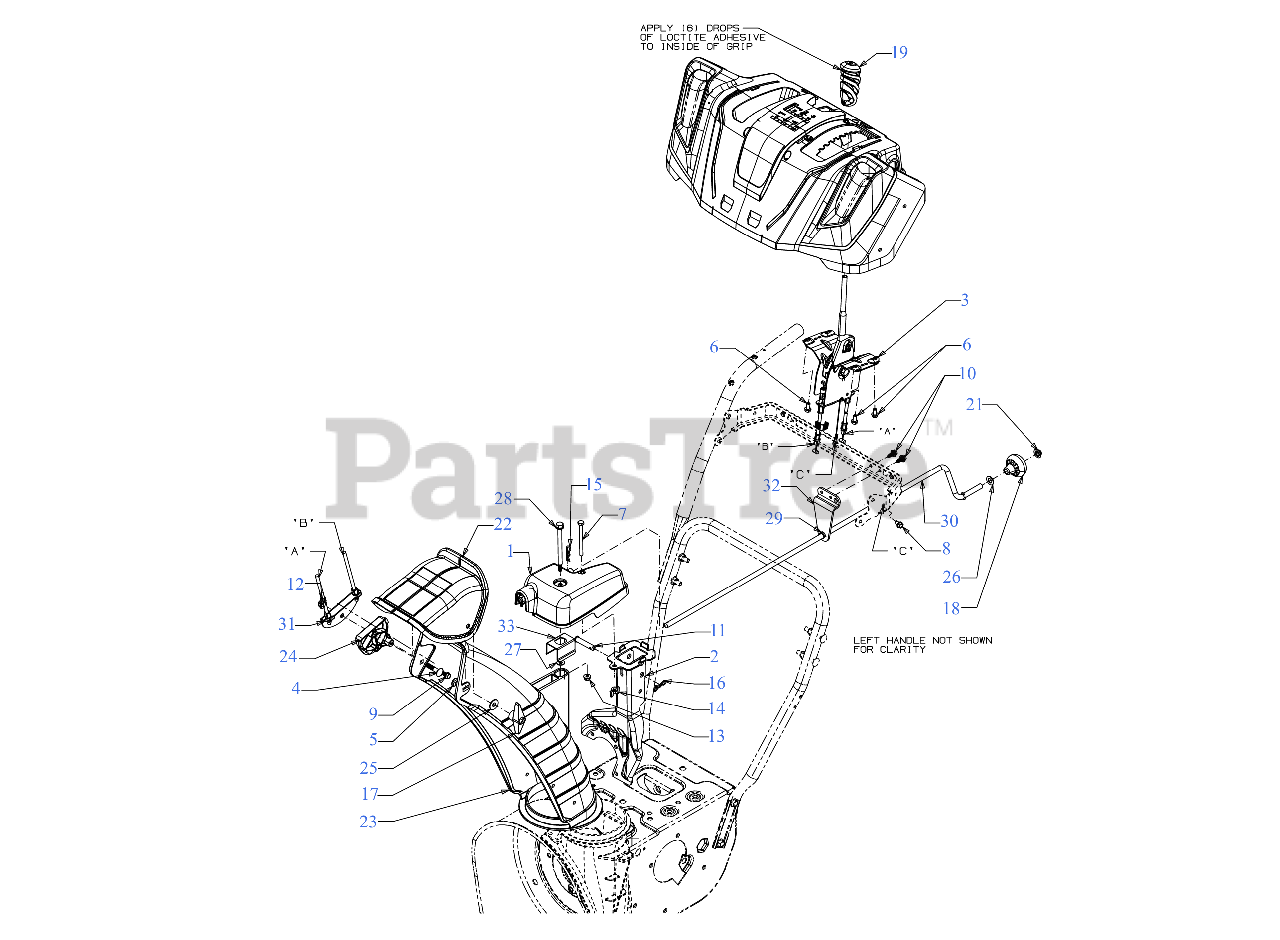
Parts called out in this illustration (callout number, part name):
1	GEARBOX ASSEMBLY
3	CHUTE CONTROL
4	CARRIAGE BOLT 5/16-18 x 1.50
5	CARRIAGE BOLT 5/16-18 x 1
6	HEX SCREW 1/4-15 x .50
7	SCREW 1/4-20 x 3.0 GR5
8	SCREW 1/4-20 X.500
9	SCREW 1/4-15 x .750
10	SCREW 1/4-20X.625
11	CLEVIS PIN 3/8 x 1.87
12	FLANGE LOCK NUT 5/16-18
13	FLANGE LOCK NUT
14	WING NUT 1/4-20
15	INTERNAL COTTER PIN-1/2 DIA
16	BOW TIE COTTER PIN 1/4-5/16
17	WING KNOB NUT
18	SHIFT KNOB
19	PTO HANDLE GRIP .355 ID
21	PUSH NUT
22	UPPER CHUTE
23	LOWER CHUTE 5"
24	CABLE CHUTE GUIDE
25	FLAT WASHER
26	FLAT WASHER
27	FLAT WASHER
28	SHOULDER SCREW
29	BUSHING .380 ID
32	ROD SUPPORT BRACKET
33	CHUTE BRACKET
